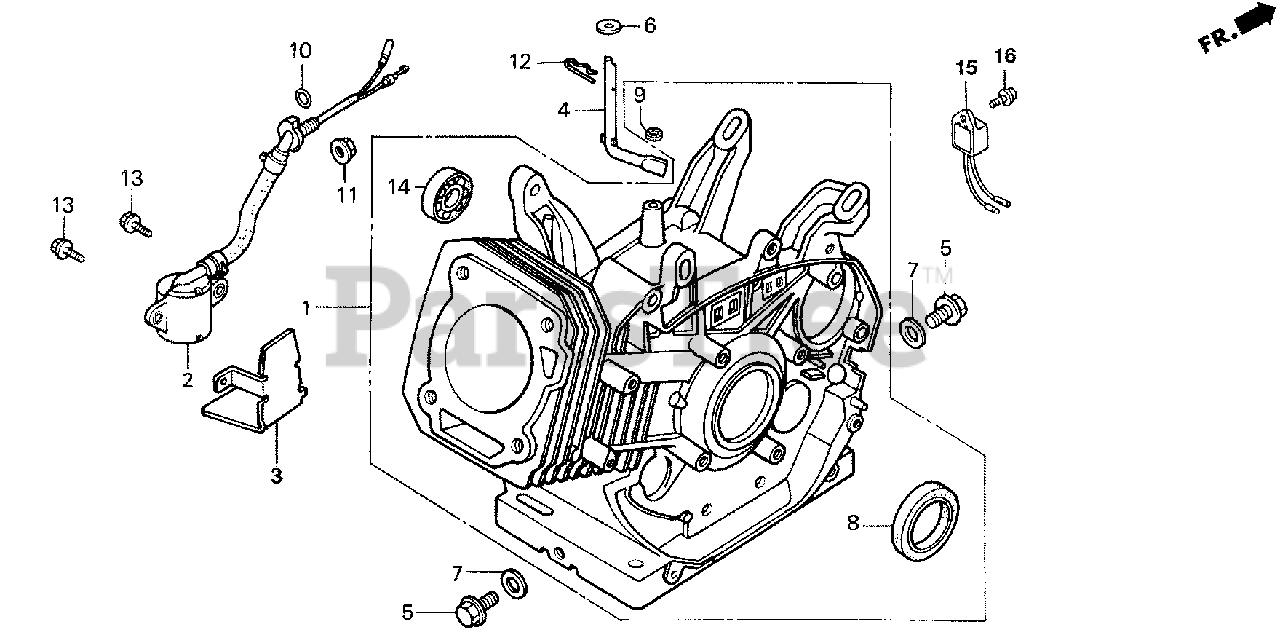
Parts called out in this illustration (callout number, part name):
1	CYLINDER ASSY.
2	SWITCH ASSY., OIL LEVEL
3	PLATE, OIL LEVEL SWITCH
4	SHAFT, GOVERNOR ARM
5	BOLT, DRAIN PLUG (12X15)
5	BOLT, DRAIN PLUG
6	WASHER (8.2X17X0.8)
7	WASHER, DRAIN PLUG (12MM)
8	OIL SEAL (35X52X8)
9	OIL SEAL (8X14X5)
10	O-RING (13.5X1.5) (ARAI)
11	NUT, FLANGE (10MM)
12	PIN, LOCK (10MM)
13	BOLT, FLANGE (6X12)
14	BEARING, RADIAL BALL (6202)
15	ALERT UNIT, OIL
16	BOLT, FLANGE (6X12) (CT200)
